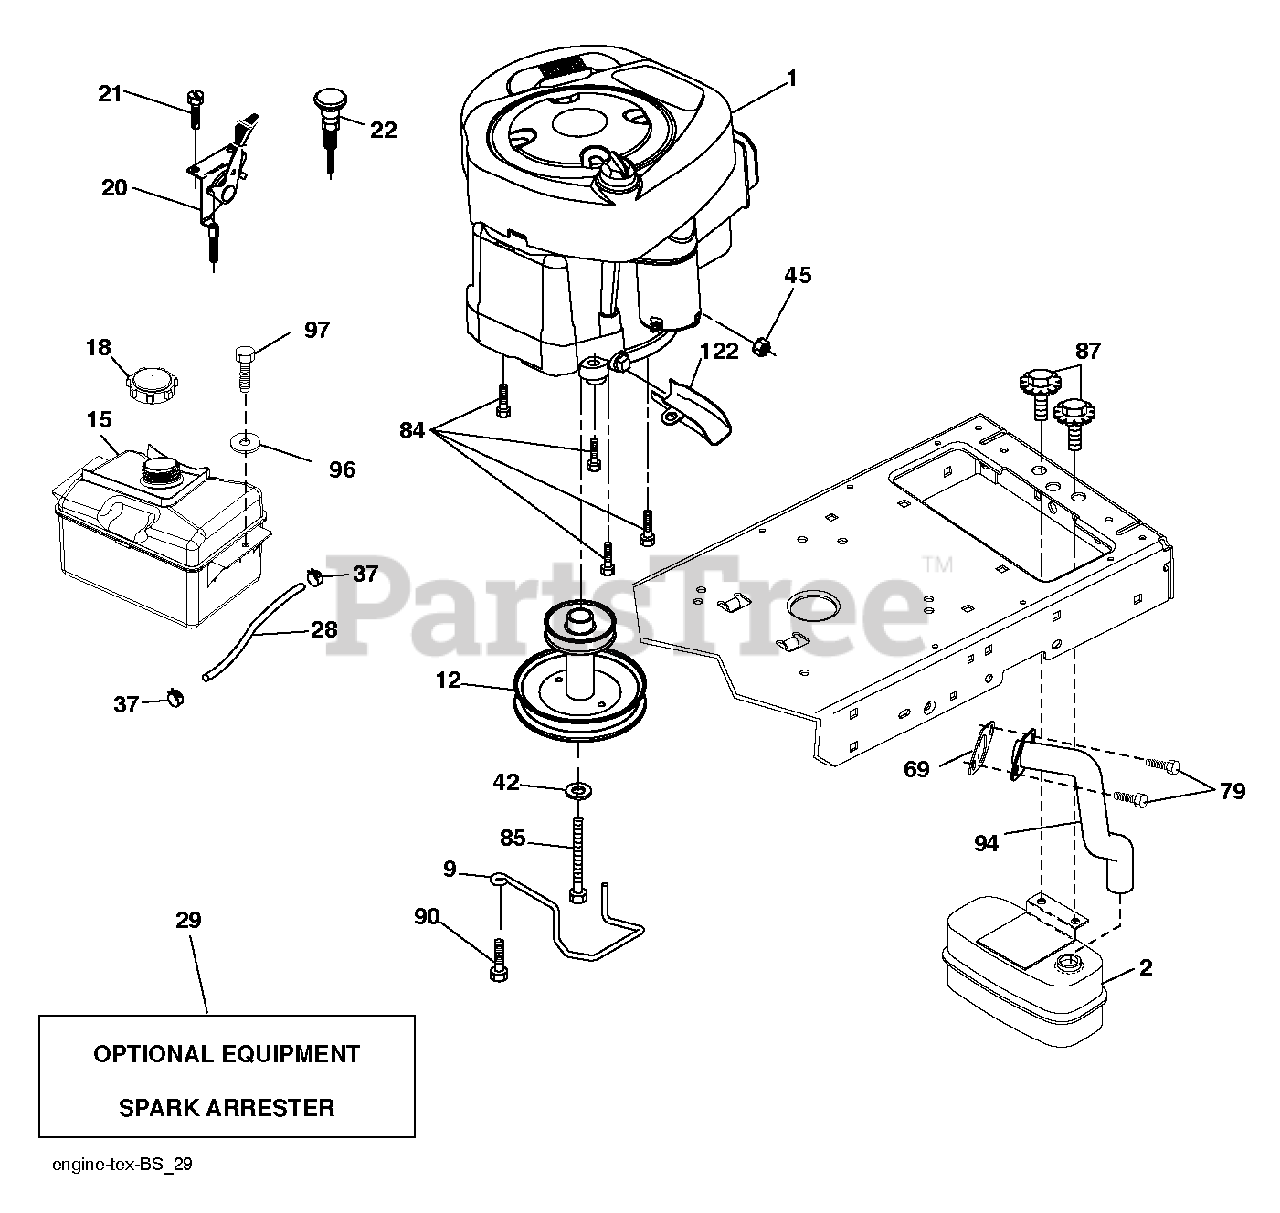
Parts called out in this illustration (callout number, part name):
2	MUFFLER.SINGLE.CYL.KOHL/B&S
9	KEEPER.BELT.ENGINE.3.25
12	PULLEY ENGINE
15	TANK FUEL FRT 1.5 GAL
18	CAP ASM.FUEL.2.25"FR.
20	CONTROL.TH/CK.C.
21	SCREW.#10 X 0.750.BOS THREAD
28	LINE.FUEL.20
29	ARRESTER SPARK (OPTIONAL)
37	HOSE CLAMP
42	LOCKWASHER
45	NUT
69	REPL BY 532 27 22-93
79	SCREW.SOCKET HD.5/16-1
84	SCREW.3/8-16
85	BOLT HEX 7/16-20X4-1/4"
87	BOLT, 5/16-18 X 1 3/4
90	SCREW 3/8-16X1
94	EXHAUST.TUBE.B&S.
97	SCREW HEXWSHR 1/4-20X3/4
122	EXTENSION DRAIN OIL
